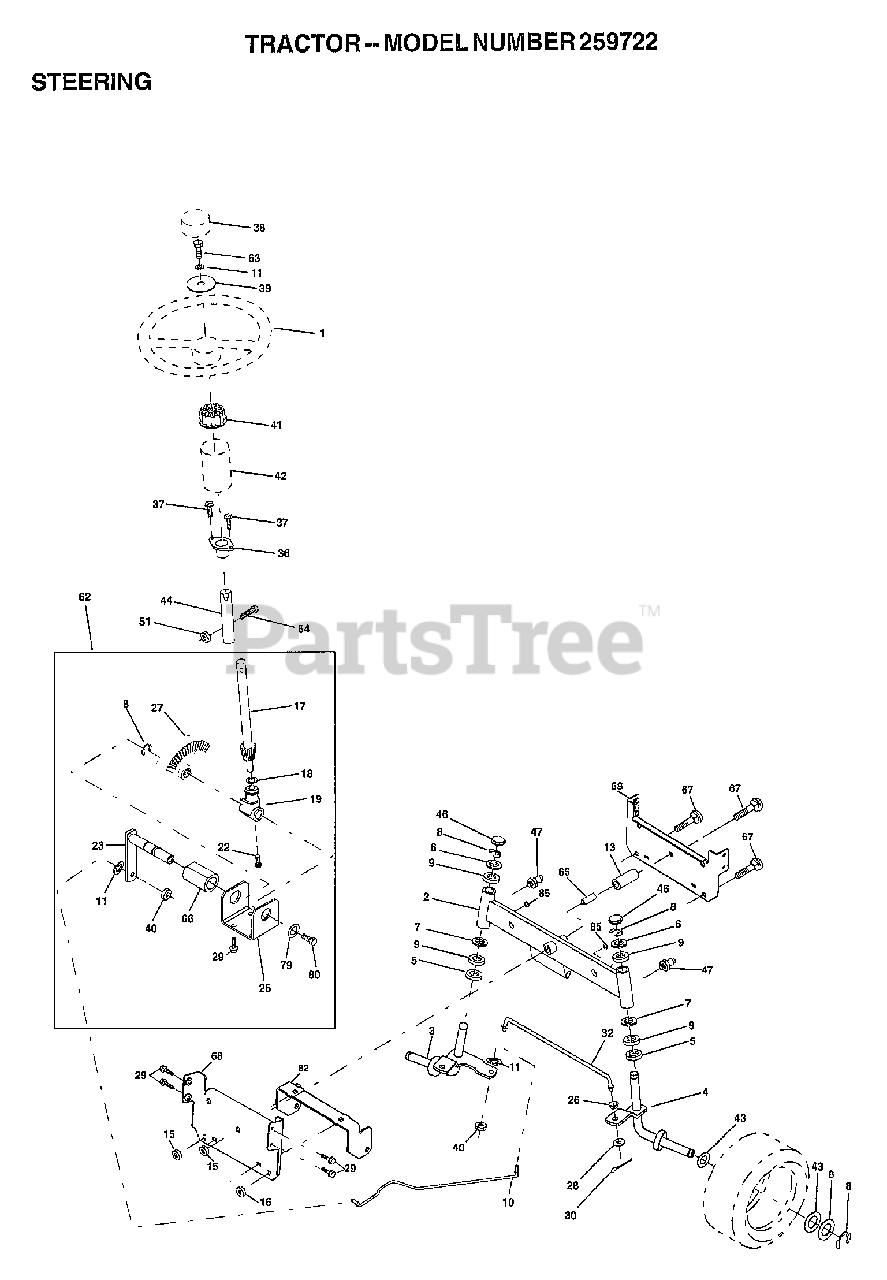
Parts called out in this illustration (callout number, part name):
1	WHEEL STR AYP BLK
2	AXLE ASM
3	SPINDLE.ASM.LH
4	"SPINDLE ASM,RH"
5	WASHER .T
6	WASHER
7	WASHER
8	RING
9	COL. SRTG. BEAR.
10	LINK DRAG
11	LOCKWASHER
13	SPACER BEARING
15	NUT.HXFLG.LOCK.
17	SHAFT ASM STEERIN
18	THRUST WASHER
19	SUPPORT.SHAFT.STEER
22	SCREW.HX.WSH.HD
23	SHAFT.ASM.PITMAN
25	BRKT-STEERING
26	BUSHING.DRAGLINK
27	GEAR SECTOR
28	WASHER
29	SCREW
30	COTTER PIN
32	TIE ROD
36	BUSHING.STEERING
37	"SCREW-TT,10-32 FL"
38	CAP STEER AYP
39	WASHER
40	GRIPCO NUT
41	ADAPTER LT
42	BOOT.STEERING.DASH.P/L
43	WASHER
44	EXT SHAFT STEERIN
46	CAP
47	ZERK M
51	NUT
54	BOLT
62	KIT.STEER.ASM
63	BOLT
65	"SPACER BRCAE,AXLE"
66	"BEARING-ARM,PITMA"
67	BOLT RDHD 3/8-16
68	BRACE AXLE
79	WASHER
80	BOLT.HX.NYLON3/8-16X3/
82	BRKT SUSP CHASSIS FRT
85	XMAS TREE FASTNER
